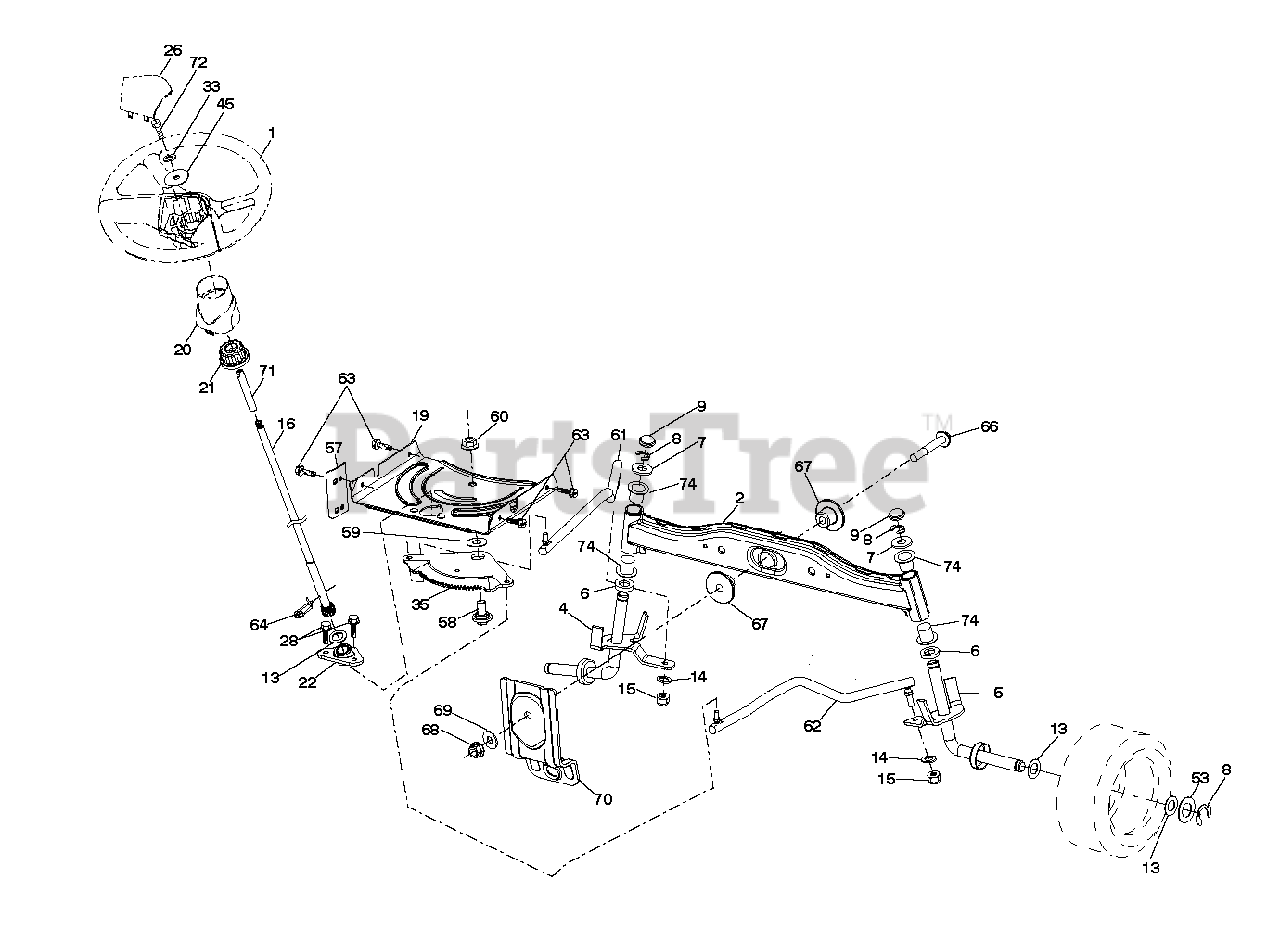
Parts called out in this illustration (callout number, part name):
1	WHEEL.STEERING.HARD.RIM.BLAC
2	AXLE HALF ASM-WELDED
4	Spindle Assembly, LH 13"
5	Spindle Assembly, RH 13"
14	WASHER, LOCK 3/8
15	NUT CROWNLOCK 3/8-24
16	SHAFT.STEER.3/4.PLATED.TEX
19	PLATE.STEER.DDL.NLT/NG
20	BOOT.STEERING.PREDATOR.LT.BLAC
21	ADAPTER, WHEEL STNG..
22	STEERING.SUPT.LOWER.
26	INSERT, WHEEL STEERING
28	SCREW, 3/8-16X3/4
35	GEAR.SECTOR.PLATE.DDL.
53	WASHER.HARDENED
57	BRACKET.UPSTOP.TEX
58	BOLT.SHOULDER.SECTOR.P
59	WASHER.THURST.SECTOR.S
60	NUT FLANGE LOCK 5/8-11
61	DRAGLINK.LH.BALLSTUD.D
62	DRAGLINK.RH.BALLSTUD.D
63	SCREW
64	RETAINER.CLIP.SPRING.S
66	BOLT HEX FGHD 7/16-14 X 3 SERR
67	BUSHING.PM.FRONT AXLE
68	NUT.LOCK.FLANGE.7/16
69	WASHER.1.5X.505X.118
70	Suspension Bracket, Front 30" Srd
71	SHAFT.EXTEN.STRG.SPLINE
72	BOLT 5/16-18 X 4 W/PATCH
74	BRNG T
